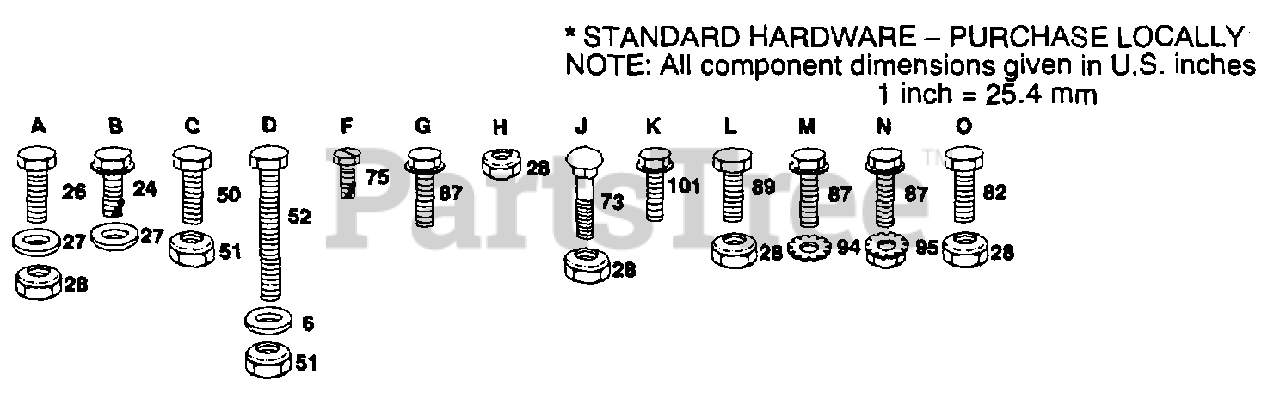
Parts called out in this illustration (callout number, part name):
6	WASHER
24	SCREW
26	BOLT
27	WASHER
50	BOLT
52	BOLT HEX
67	RETAIN BELT
73	BOLT
75	SCREW LT
82	BOLT
87	SCREW LT
94	LOCKWASHER
95	NUT
101	SCREW
